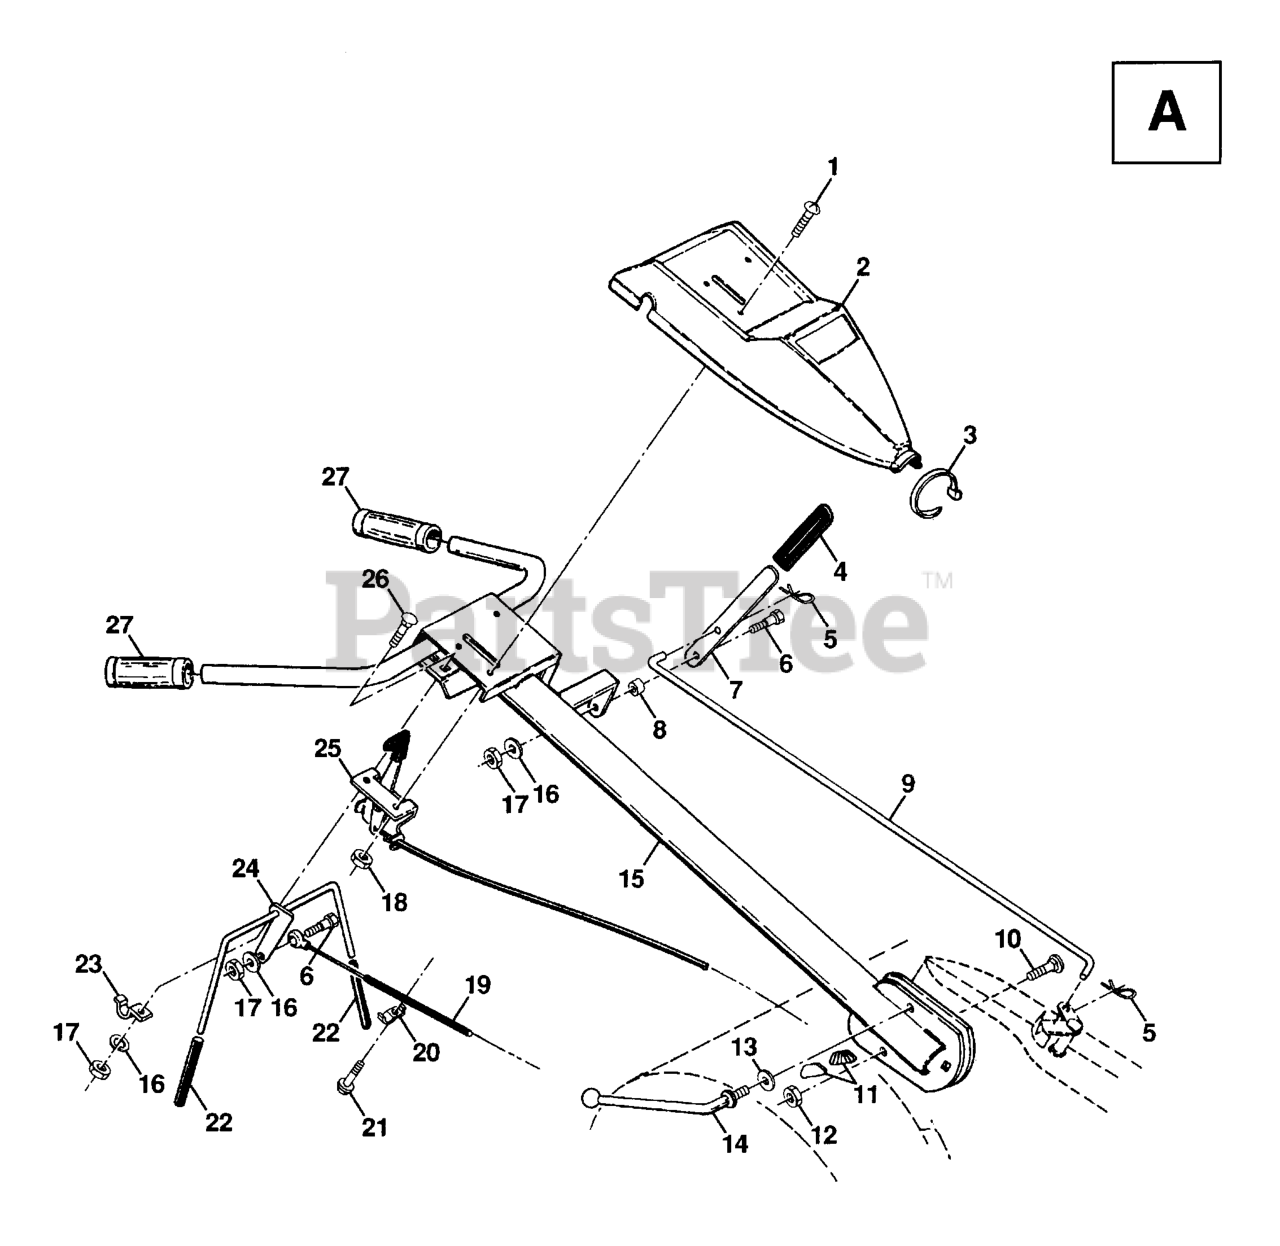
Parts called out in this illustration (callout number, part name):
1	SCREW
3	TIE CABLE CRT
4	GRIP T
5	RETAINER M
6	SHOULDER BOLT ST
7	SHIFT HANDLE CRT
8	GROMMET.RUBBER.CRT.TILLER
9	SHIFT ROD CRT
10	BOLT D
11	LOCK.HANDLE.CRT
12	LOCKNUT
13	WASHER CRT
14	LEVER.LOCK.CRT
15	HANDLE
16	LOCKWASHER
17	NUT
18	NUT **
19	CABLE CLUTCH CRT
20	CONDUIT.CLIP.PLATED
21	SCREW
22	GRIP BAR CRT(1)
23	CLAMP.BAR.CRT.BLACK
24	BAR ASSY CONTROL
25	CONT,THROTTLE
27	HAND.GRIP.NLA
